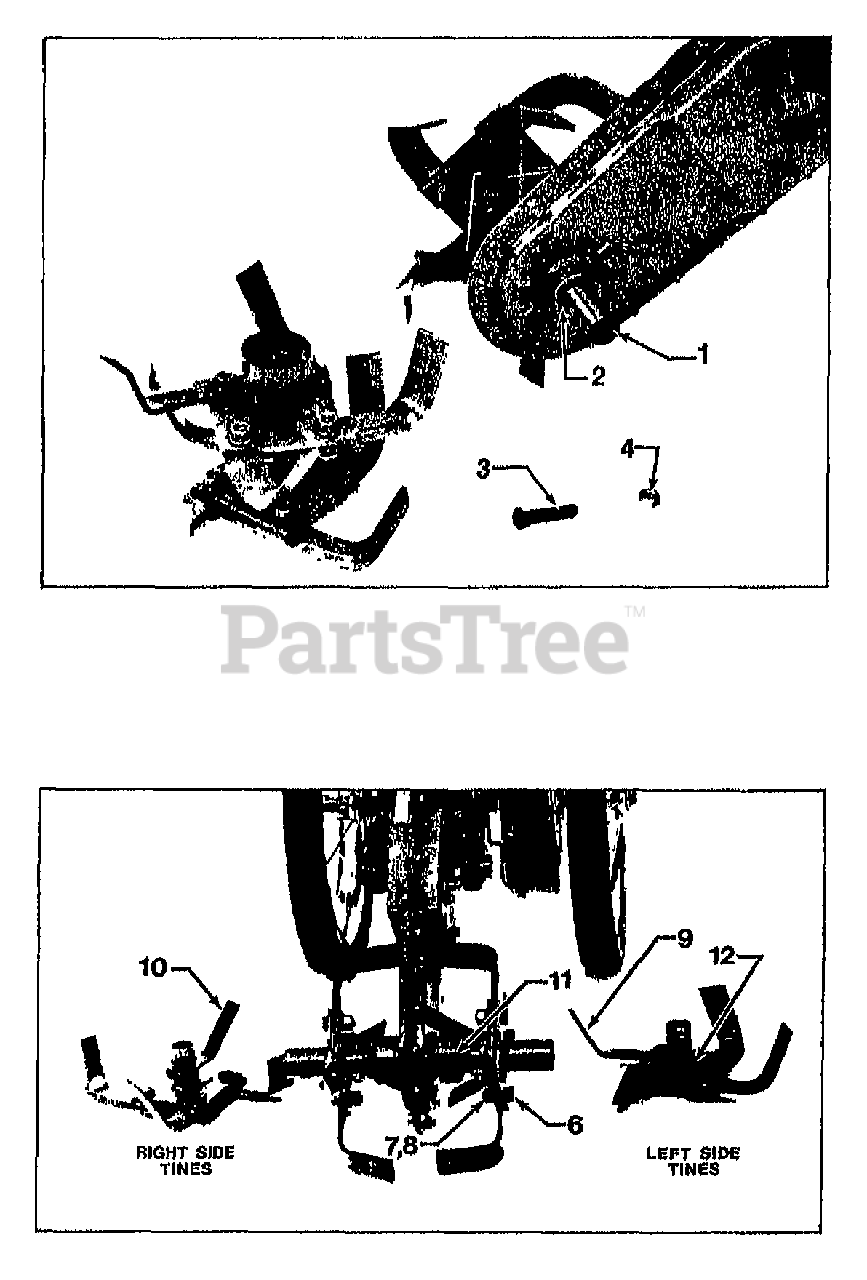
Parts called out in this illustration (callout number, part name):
1	TINE SHAFT-WELD
2	SEAL-OIL
3	BOLT-HH 3/8-16X1.75 G8 ZP (ATTACHES TINE HOLDERS TO TINE SHAFT)
4	NUT-H/LK 3/8-16
6	SCR-HH 3/8-16X1.0 G5 ZP (ATTACHES TINES TO TINE HOLDERS)
7	WASHER-LK .375 @ DEPL
8	NUT-HEX 3/8-16 ZP
9	TINE-BOLO LT
10	TINE-BOLO RT
11	TINE HOLDER-INNER WELD
12	TINE HOLDER-OUTER WELD
